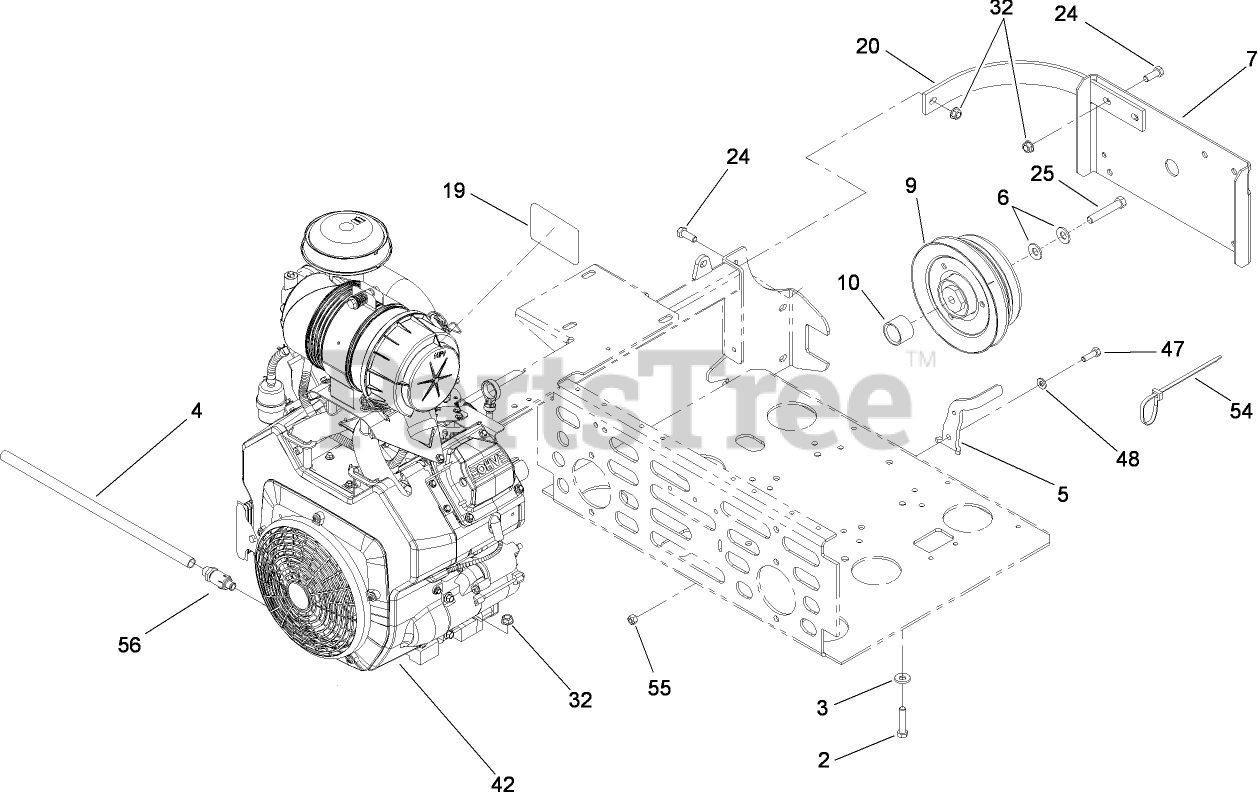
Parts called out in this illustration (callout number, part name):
2	SCREW-HH
3	WASHER-BELLEVILLE
4	TUBE-DRAIN, OIL
5	ANCHOR-CLUTCH
6	WASHER-SPRING
7	GUARD-CLUTCH
9	CLUTCH-SPOT BRAKE
10	SPACER-CLUTCH
20	STRAP-GUARD
24	SCREW-HH
25	SCREW-HH
32	NUT-HHF, WHIZ
47	SCREW-HH
48	WASHER-SPRING
54	TIE-PLASTIC
55	NUT-LOCK, NI
56	VALVE-DRAIN, OIL
